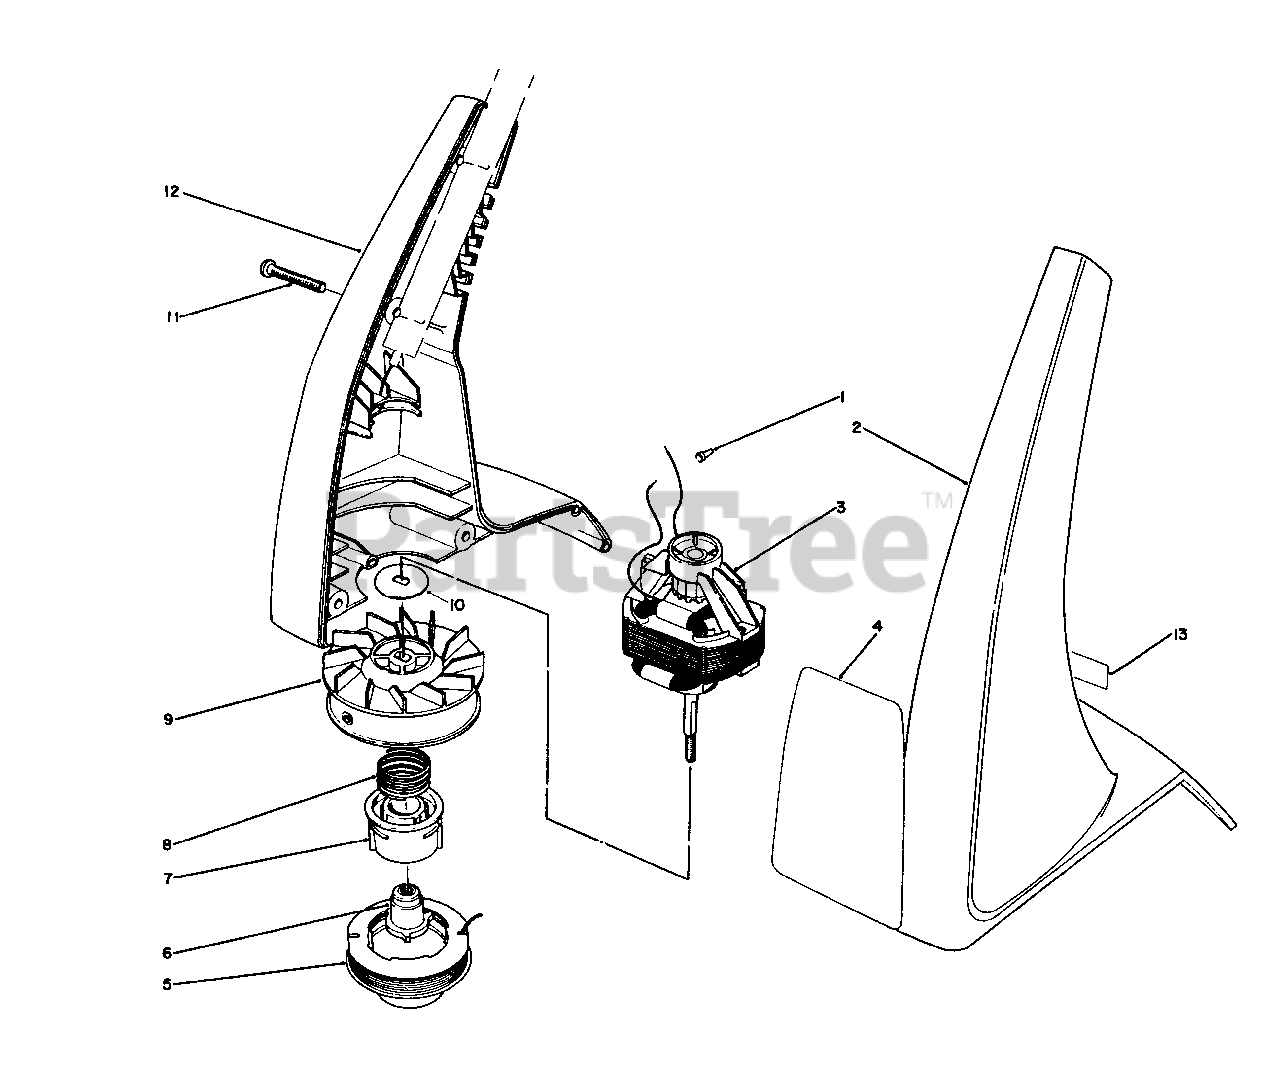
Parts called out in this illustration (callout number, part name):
1	Connector-Wire
2	Housing-L.H.
5	12 Ft. .050 Dia. Cutting Line Prewound on Spool
7	Spool Core
8	Spring
9	Drum w/Eyelet
10	Washer-Motor
11	Screw
12	Housing-R.H.
13	Decal-Made In Canada
